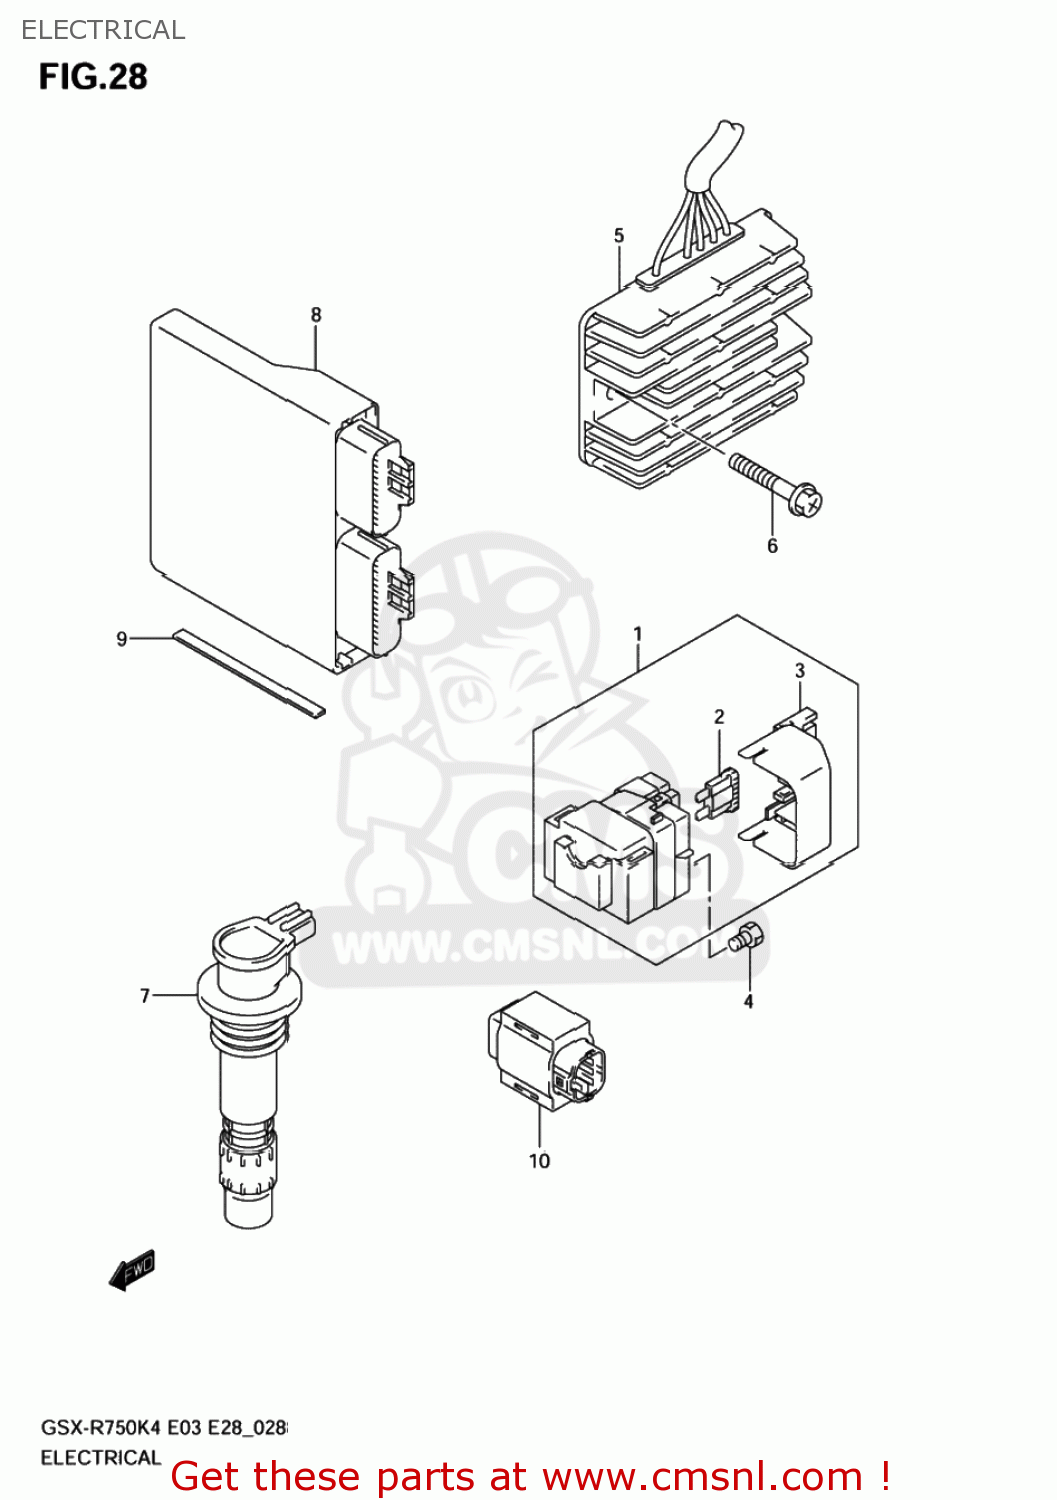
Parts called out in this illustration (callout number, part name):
1	RELAY ASSY,STARTING MOTOR
2	FUSE(30A)
3	COVER,STARTER RELAY
4	SCREW(6X8)
5	RECTIFIER ASY
6	SCREW
7	COIL ASSY,IGNITION
8	CONTROL UNIT,FI
9	CUSHION(130X10X2)
10	SENSOR ASSY,FUEL CUT
